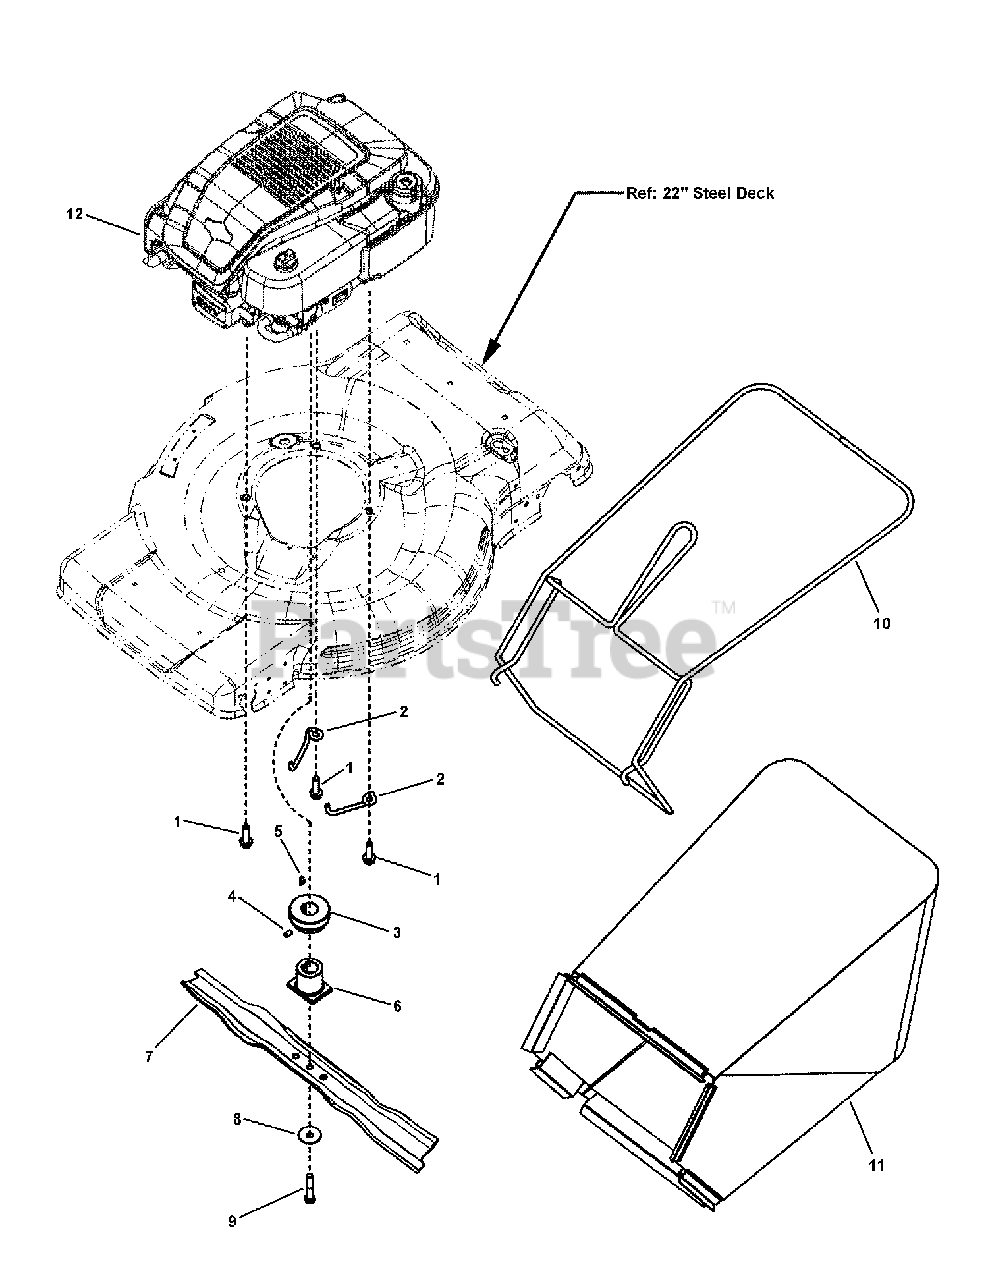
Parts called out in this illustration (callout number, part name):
1	SCREW, 3/8-16 x 1-1/4" Hex Washer Self-Tap
2	BELT GUIDE, Engine
3	PULLEY, Engine
4	SET SCREW, 5/16-18 x 1/2" Hex Recess
5	KEY, #HP-506 Hi-Pro
6	BLADE HUB, 21" WBM, Rear Drive, 2 Position
7	BLADE, Wave, Steel Deck
8	WASHER, Cone
9	SCREW, 3/8-24 x 2" Hex Head Cap, GR 5
10	BAG FRAME, Rear Discharge (weldment)
11	GRASS BAG, 22" Rear Discharge
12	* ENGINE, W-14, 875 Series, MY Mower
12	* ENGINE, W-14, 875 Series, MY Mower FC/CAL
12	* ENGINE, W-14, 875 Professional Series (Euro)
